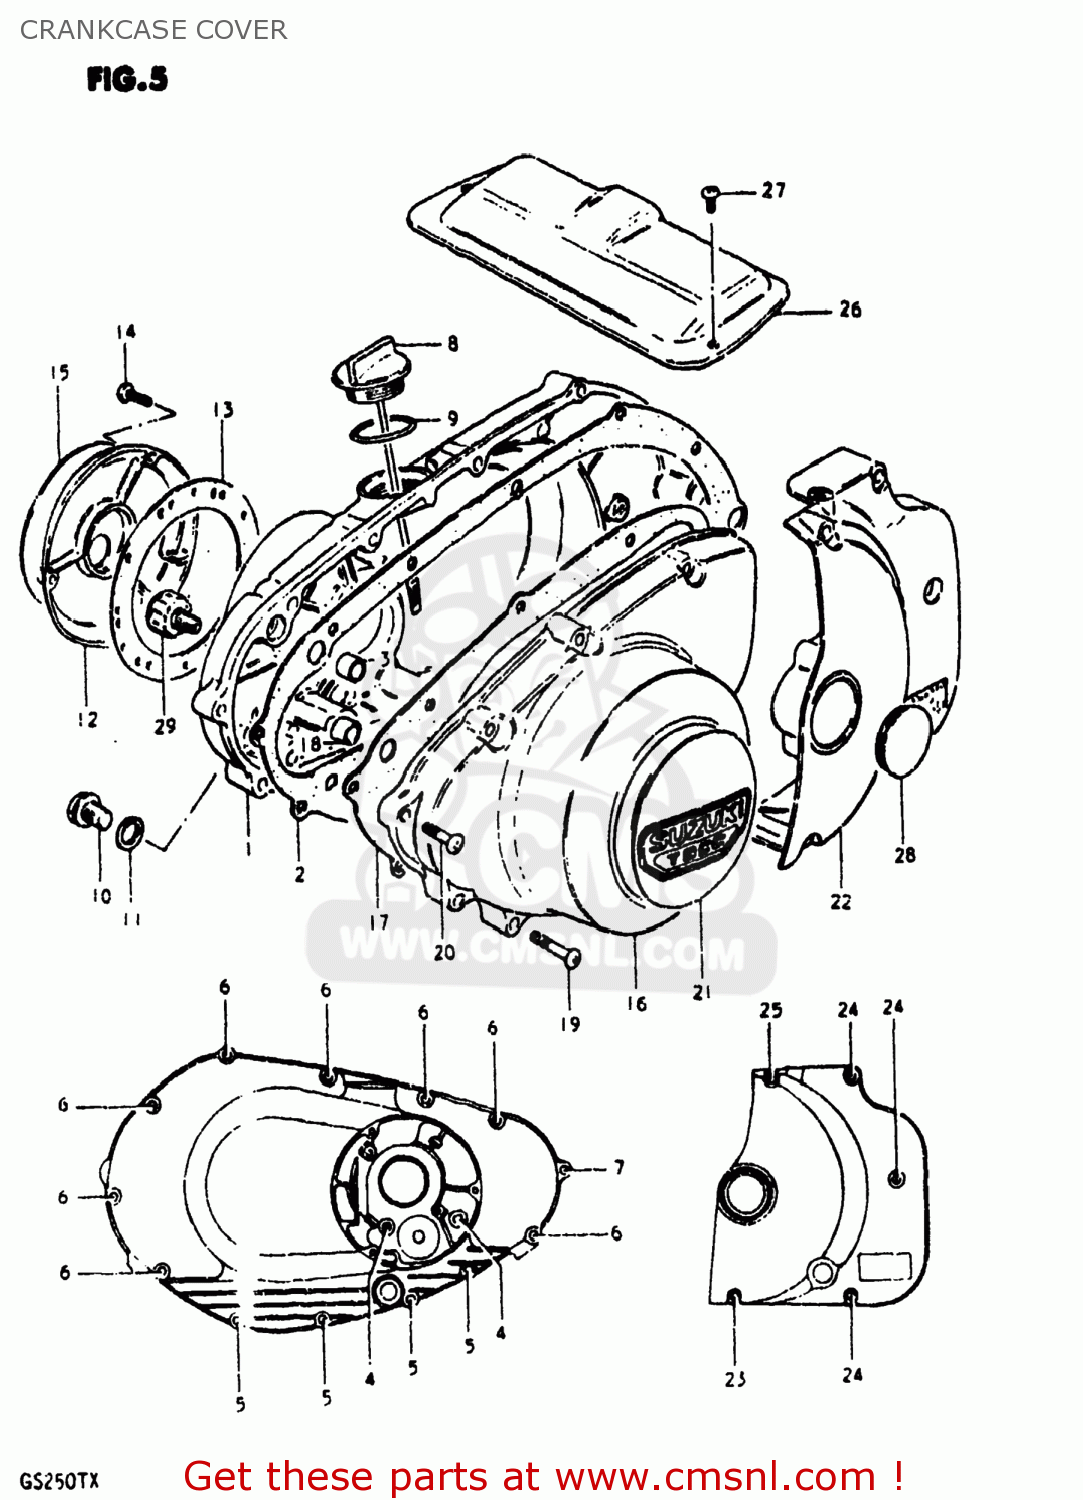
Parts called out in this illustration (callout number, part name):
1	COVER,CLUTCH
2	GASKET,CLUTCH COVER (MCA)
3	PIN
4	SCREW
5	SCREW (6X45)
6	SCREW (6X35)
7	SCREW
8	GAUGE,OIL LEVEL
9	O-RING
10	PLUG (14X12)
11	GASKET(14X19.2X2) (NAS)
12	COVER,CONTACT BREAKER
13	GASKET,CONTACT BREAKER COVER (NAS)
14	SCREW 5X20
15	EMBLEM
16	COVER,MAGNETO
17	GASKET,MAGNETO COVER (MCA)
18	PIN
19	SCREW 6X30
20	SCREW
21	EMBLEM
22	COVER,SPROCKET
23	SCREW 6X60
24	SCREW
25	SCREW 6X30
26	COVER,STARTER MOTOR
27	SCREW
28	CAP(OD:36)
29	SWITCH ASSEMBLY
